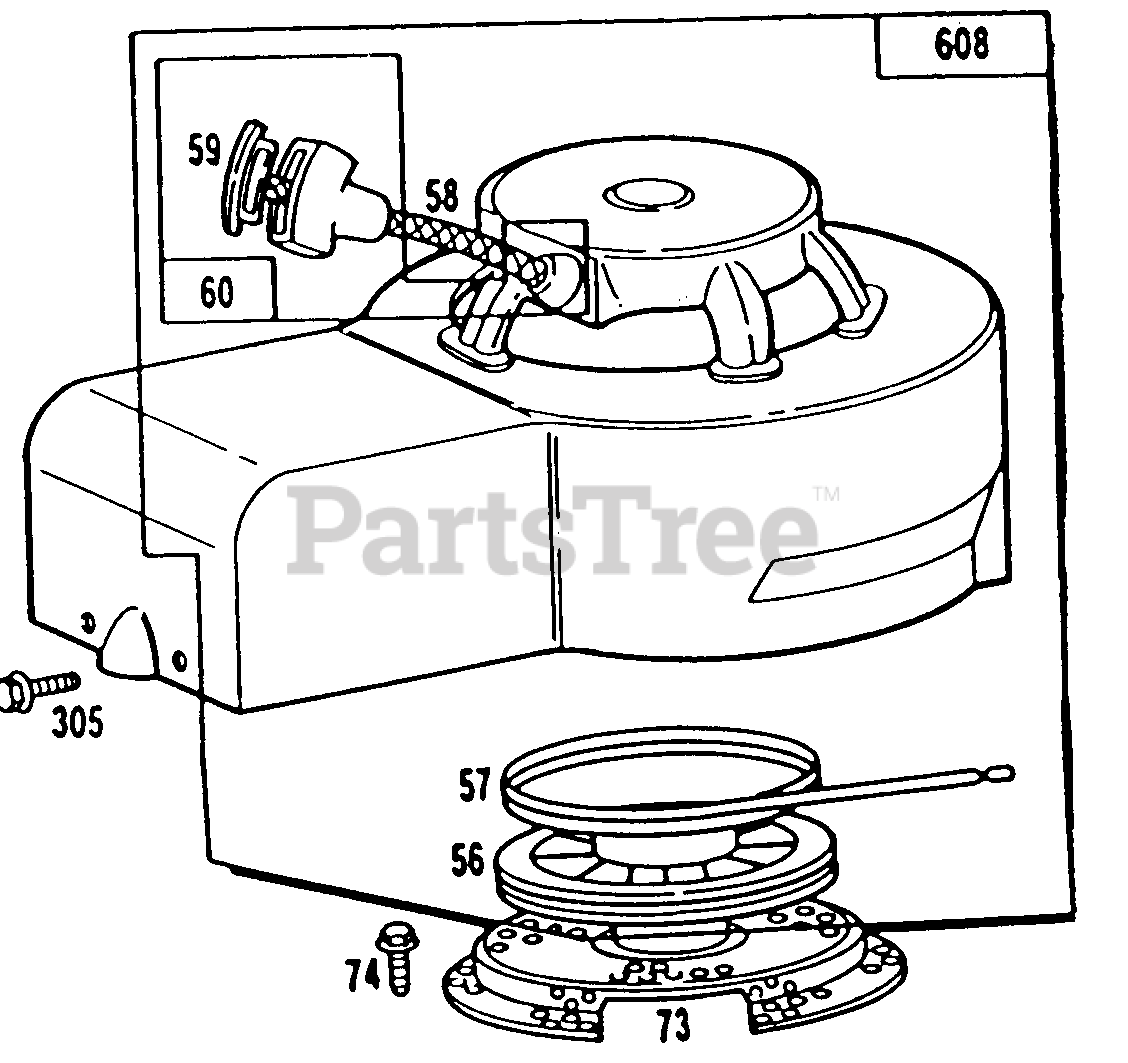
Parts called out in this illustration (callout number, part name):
56	Pulley-Starter
57	Spring-Rewind Starter
58	Rope-Rewind Starter
59	Insert-Starter Grip
60	Grip-Starter Rope
73	Screen-Starter Pulley
74	Screw-Sem
305	Screw-Blower Housing Mounting Sem
608	Starter Ass'y.-Rewind
